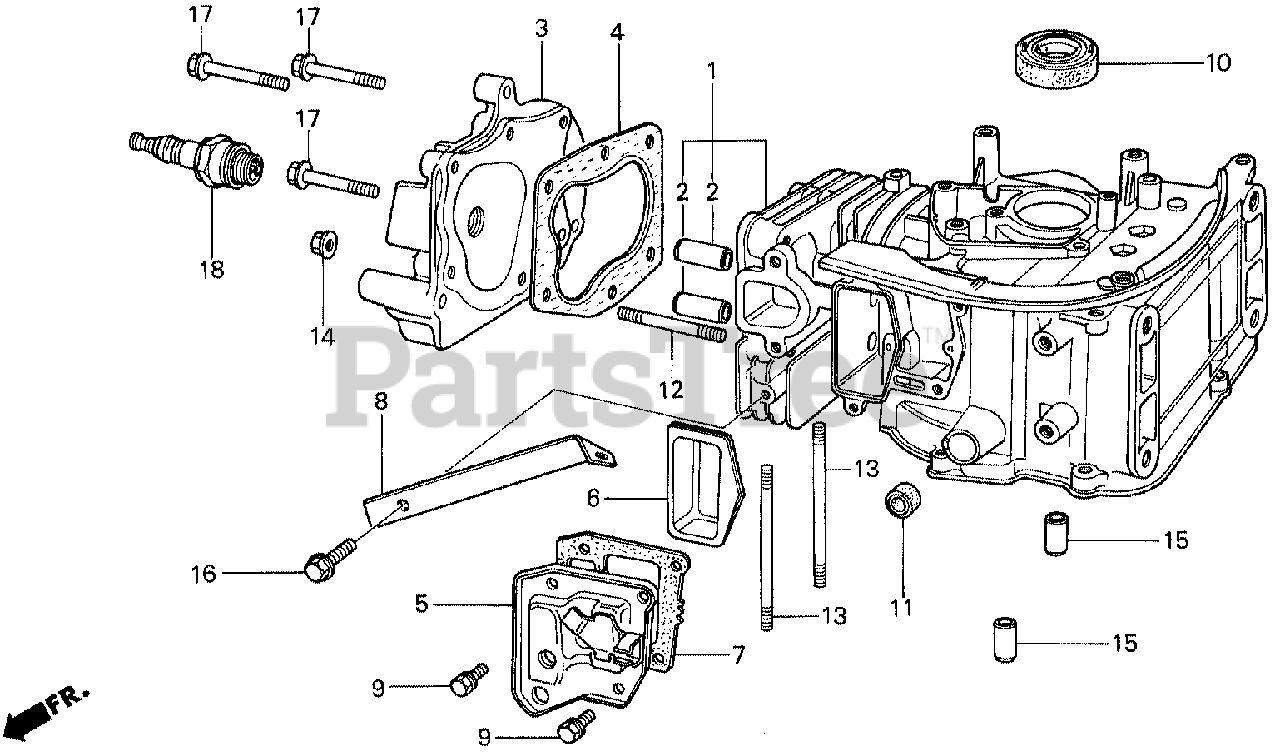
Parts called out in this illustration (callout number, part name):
1	CYLINDER
1	CYLINDER (NOT AVAILABLE)
2	GUIDE, VALVE (OVER SIZE)
3	CYLINDER HEAD (NOT AVAILABLE)
4	GASKET, CYLINDER HEAD
5	COVER, TAPPET (NOT AVAILABLE)
6	SEPARATOR (INNER)
7	GASKET, TAPPET COVER
8	BIMETAL, AUTOMATIC CHOKE
9	BOLT, FLANGE (5X10)
10	OIL SEAL (17X30X6) (NOK)
11	OIL SEAL (5X10X4)
12	BOLT, STUD (6X45) (SOURCE: VINTAGE PARTS INC.)
13	BOLT, STUD (6X80)
14	NUT, FLANGE (6MM)
15	PIN, DOWEL (8X14)
16	BOLT, FLANGE (6X12)
17	BOLT, FLANGE (6X35)
18	SPARK PLUG (BM4A) (NGK)
18	SPARK PLUG (W14M-U) (DENSO)
